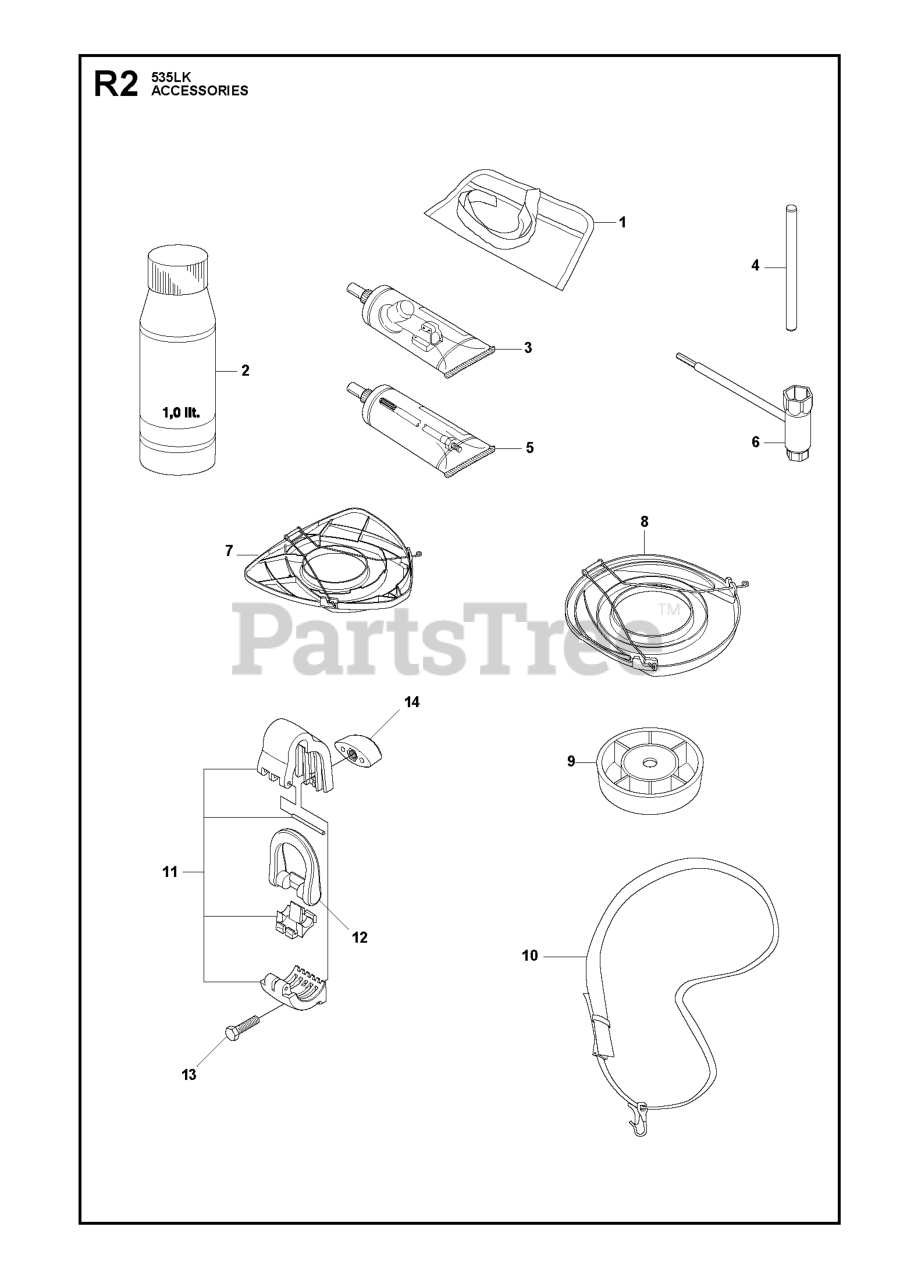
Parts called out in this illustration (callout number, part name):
2	Air Filter Oil 1l.
3	BEVEL GEAR GREASE
4	LOCKING PIN
5	DRIVE SHAFT GREASE (200 G)
6	RP COMBI TOOL
7	TRANSPORT GUARD
8	BLADE GUARD TRANSPORT
9	SUPPORT CUP
10	Harness-w/o warning
10	Harness - Diagonal with sign
11	HANGING BRACKET
13	SCREW M6S 5X20
